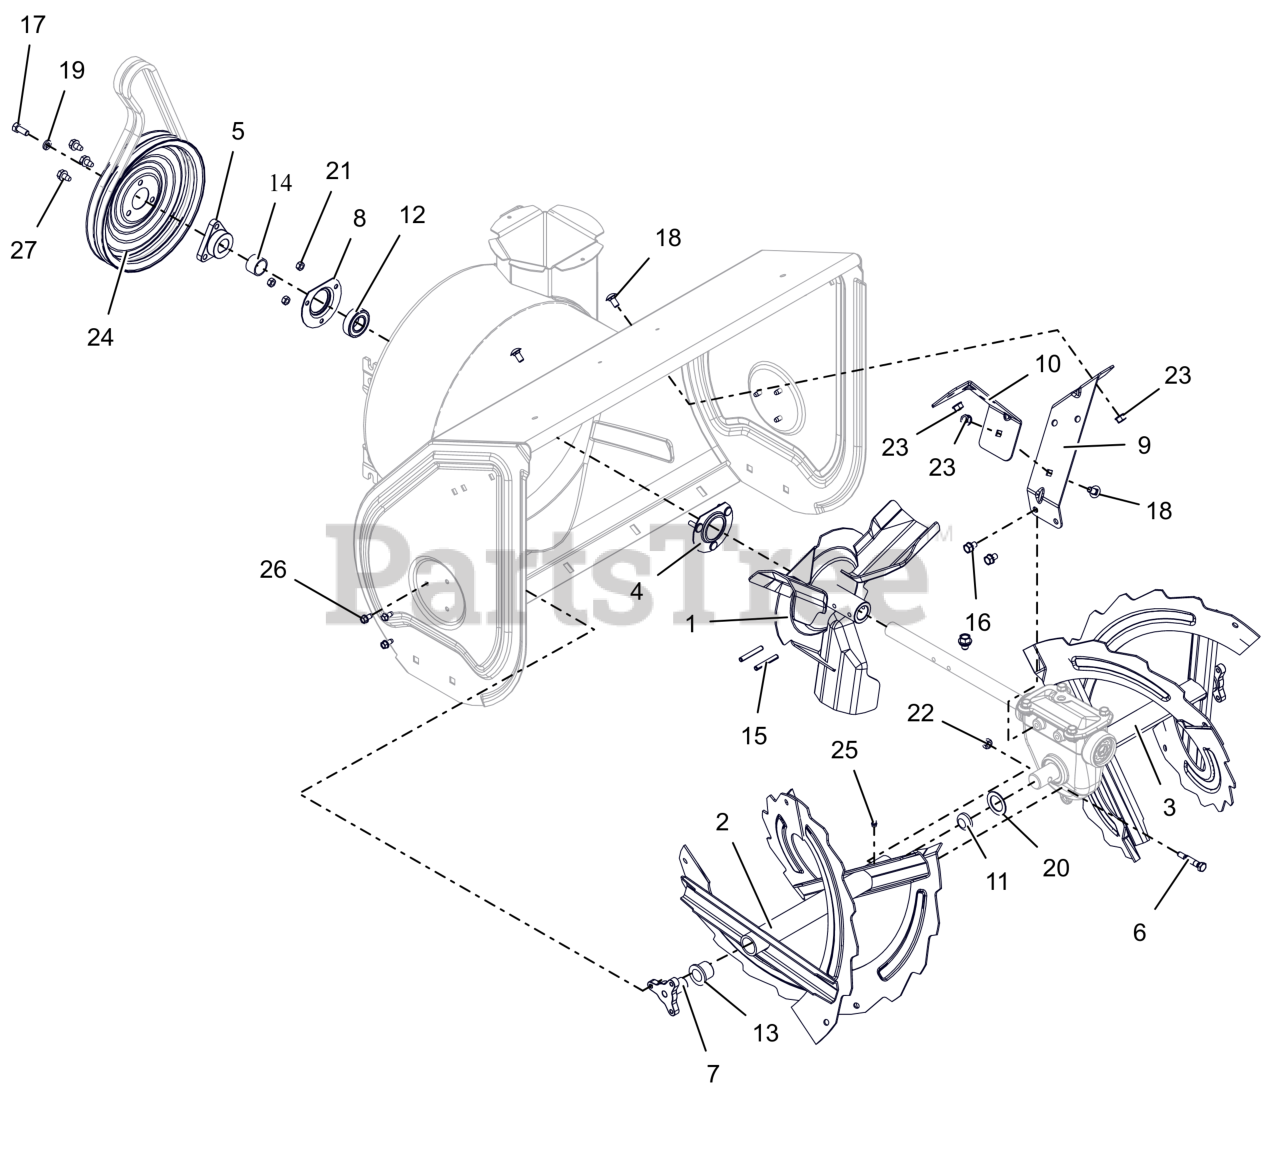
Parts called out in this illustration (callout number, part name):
1	IMPELLER, 3 BLADE-14"
2	RAKE, RH W/ZERK - 28"
3	RAKE, LH W/ZERK - 28"
4	BEARING FLANGE
5	PULLEY HUB, D-BORE .87 PRO
6	SHEAR BOLT SERVICE ASSEMBLY
7	SUPPORT, RAKE BUSHING
8	BEARING FLANGE
9	BRACKET, GEARCASE SUPPORT - LH
10	BRACKET, GEARCASE SUPPORT - RH
11	PLUG, RAKE TUBE
12	BRG-BALL .876 X 1.750 X .50
13	BSHG-FLG, NY.778 ID X 1.018 OD
14	BSHG,SPCR .895X1.065X.693
15	PIN-ROLL .250X1.75
16	BLT, SEMS .31-18X.50 G5 ZCC
17	BLT, HEX .31-24X.750 G5 ZCC
18	BLT,RHSSN.31-18X.625 G5 ZCCP30
19	WSHR, LK-HVY .312X.097 ZCC
20	WSHR, FLT 1.010X1.505X.062 ZCC
21	NUT,LK-CTR .25-20 GA ZCC
22	NUT,LK-CTR .31-18 GA ZCC
23	NUT-LK-TOP-FLG .312-18 GF ZCC
24	PULLEY, SPIN FORM DUAL GROOVE
25	ZERK,FITTING .25X.125 DRIVE IN
26	SCR-TAP .25-20X.50 HWH ZCC
27	SCR,TAP .312-18X.50 HWH TR ZCC
